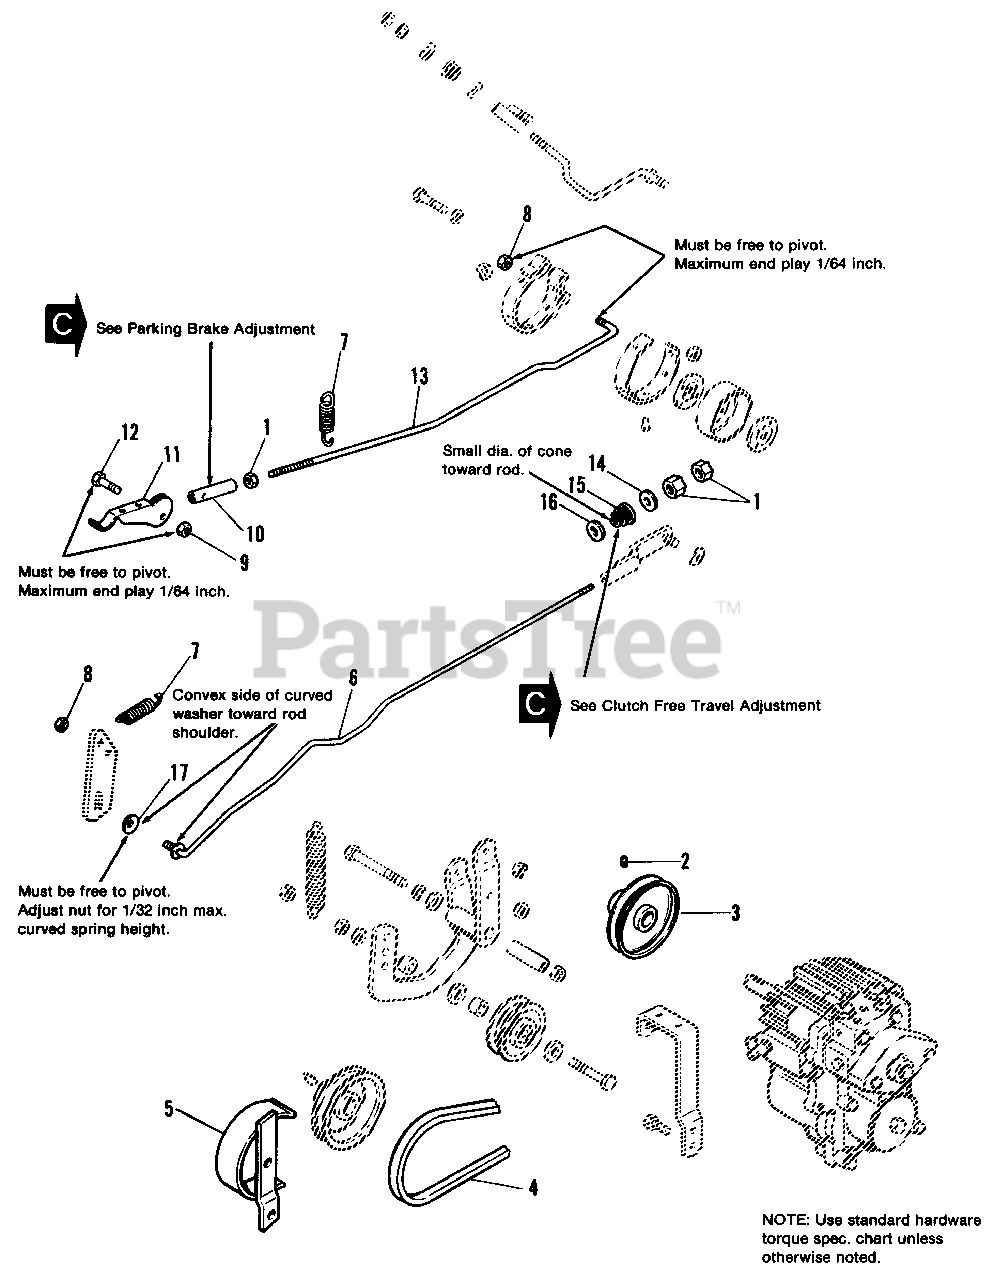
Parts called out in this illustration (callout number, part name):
1	NUT, Hex, Full, 5/16-18
2	SETSCREW, 5/16-18 x 1/2
3	PULLEY, Drive, Transmission
4	V-BELT, Drive, Transmission
5	GUARD ASSY.
6	ROD, Clutch
8	LOCKNUT, Hex, 5/16-18
9	LOCKNUT, Hex, 1/4-20
11	LEVER, Parking Brake
12	CAPSCREW, Hex Hd., 1/4-20 x 1
14	WASHER, 5/16
15	SPRING, Cone
17	WASHER, Curved, Spring
